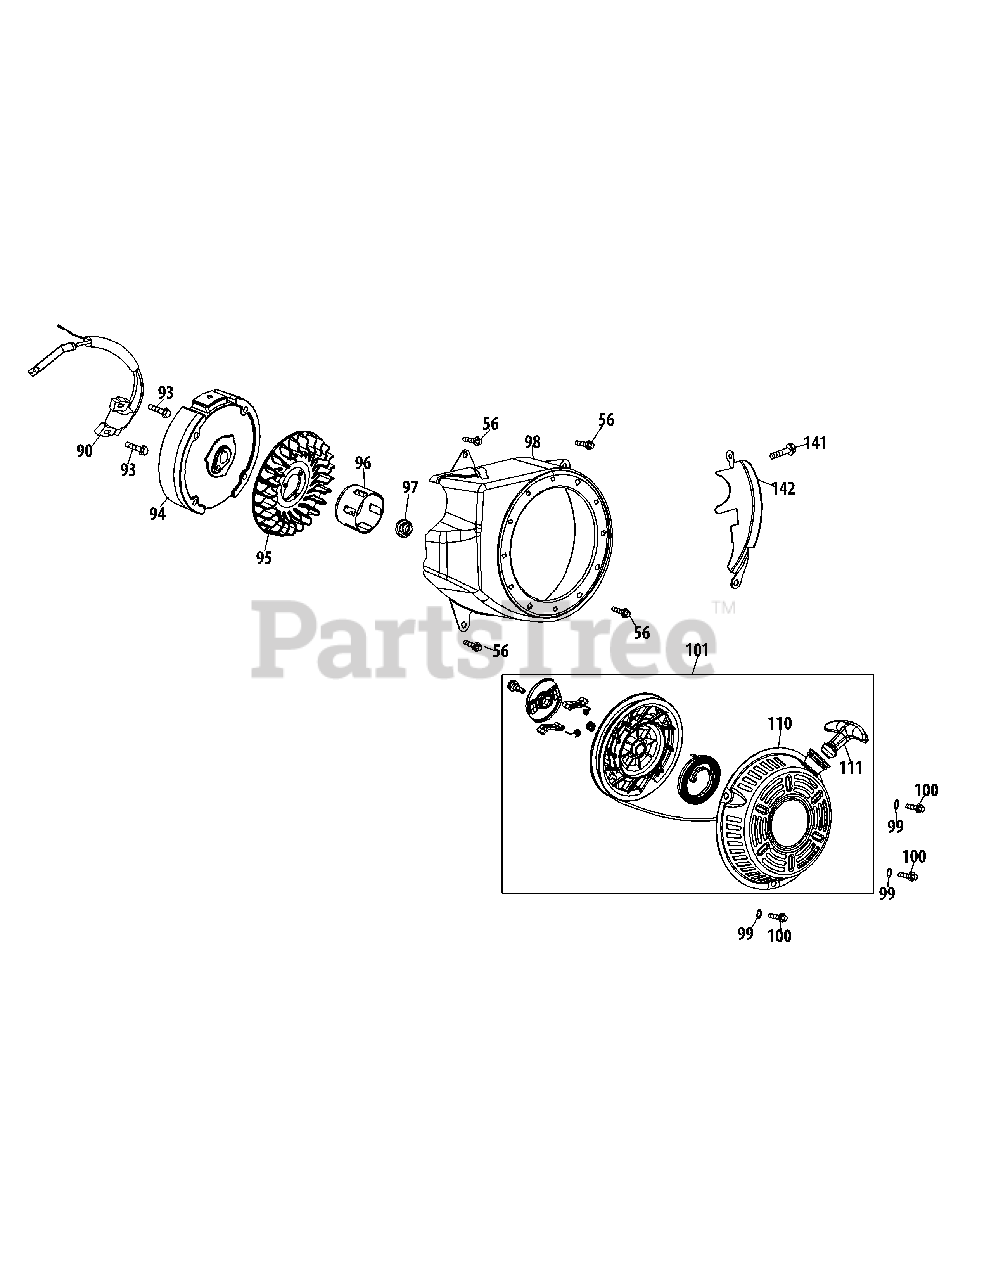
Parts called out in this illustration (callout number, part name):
56	Bolt M6×12
90	Ignition Coil Assembly
93	Bolt M6×25
94	Flywheel
95	Cooling Fan
96	Starter Cup
97	Flywheel Nut, M14 X 1.5
98	Blower Housing
99	Gasket 6
100	Bolt M6×10
101	Recoil Starter Assembly
110	Blower Housing
111	Starter Handle
141	Bolt M6×20
142	Blower Housing Shield
